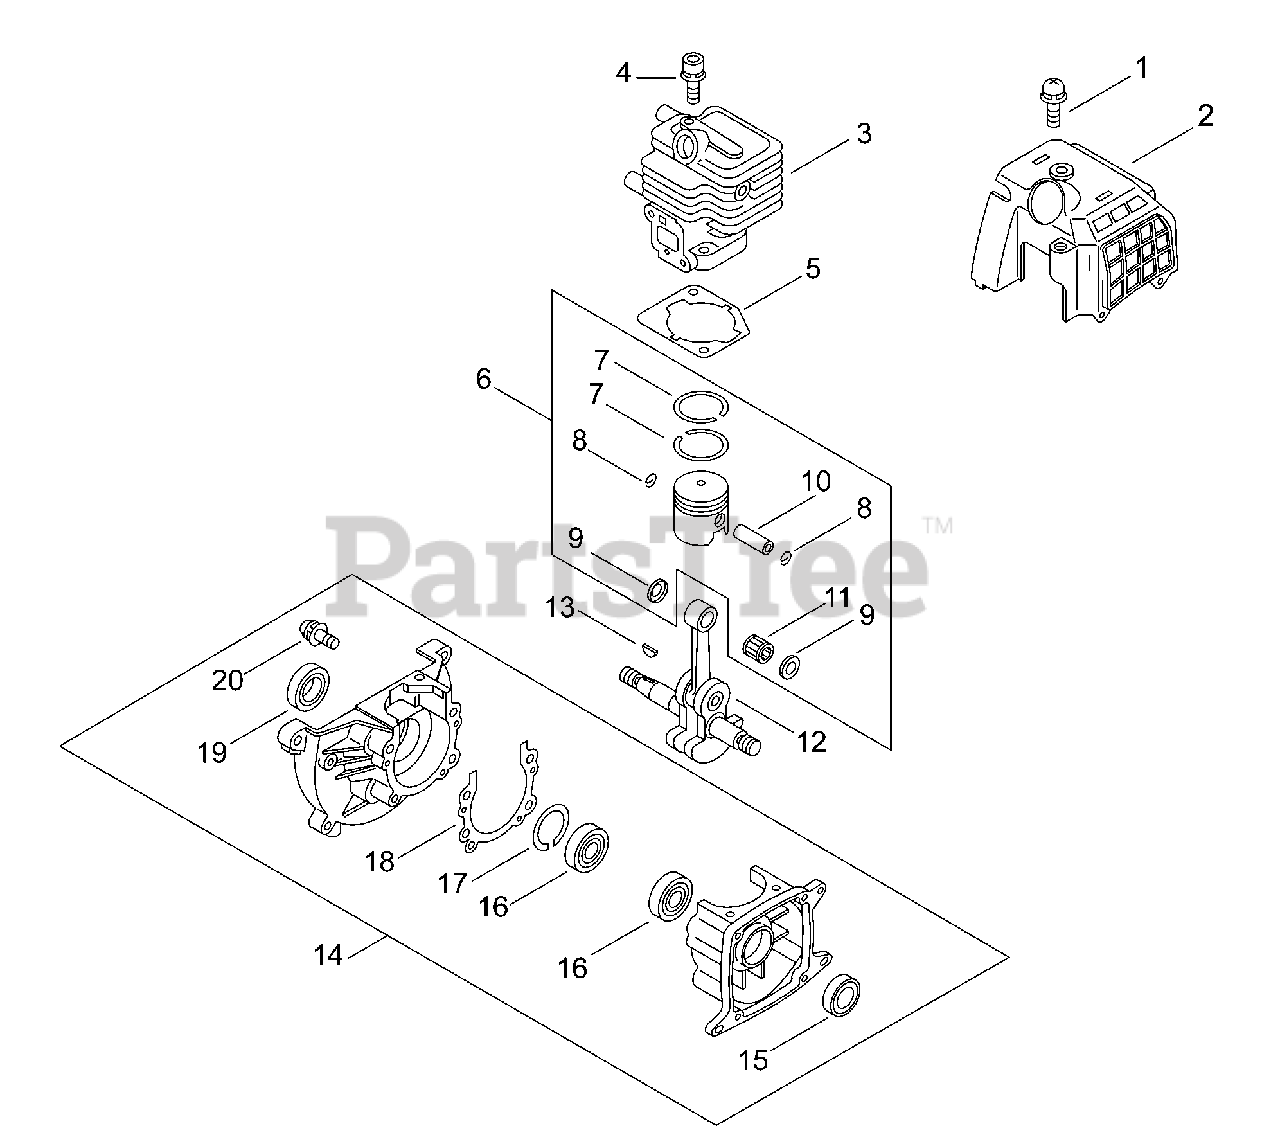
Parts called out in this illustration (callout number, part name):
1	SCREW 5×14
2	COVER, CYLINDER
3	CYLINDER
4	BOLT 5×22
5	GASKET, CYLINDER
6	PISTON KIT
7	RING, PISTON
8	RING, SNAP
9	WASHER, THRUST 8×13×2
10	PIN, PISTON
11	BEARING, NEEDLE 8
12	CRANKSHAFT
13	KEY, WOODRUFF
14	CRANKCASE KIT
15	SEAL, OIL 12
16	BEARING, BALL 6001
17	RING, SNAP 28
18	GASKET, CRANKCASE
19	SCREW 5×25
20	SEAL, OIL 12
